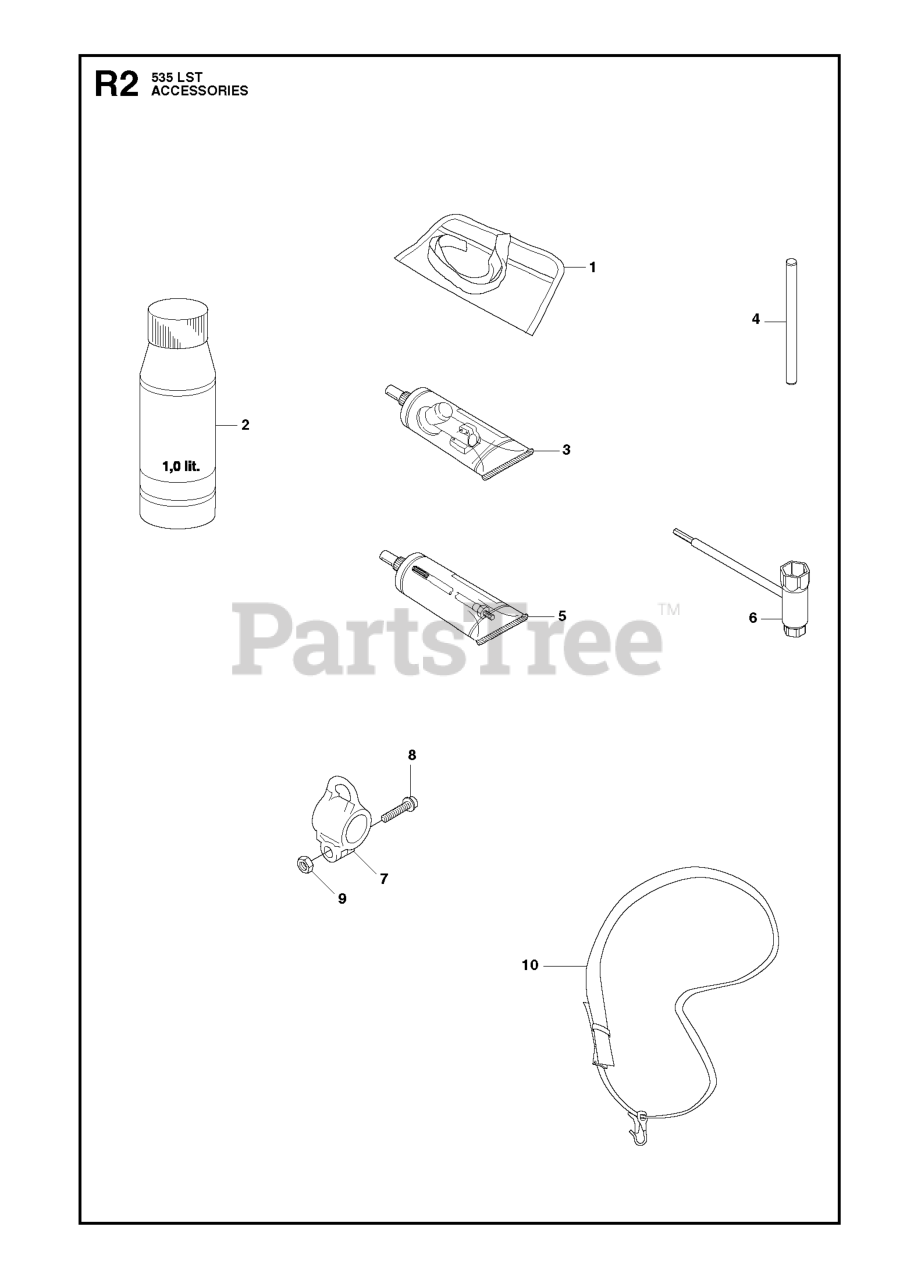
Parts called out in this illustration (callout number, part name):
2	Air Filter Oil 1l.
3	BEVEL GEAR GREASE
4	LOCKING PIN
5	DRIVE SHAFT GREASE (200 G)
6	COMBINATION WRENCH
7	HARNESS HOLDER
8	SCREW
10	Harness-w/o warning
10	Harness - Diagonal with sign
